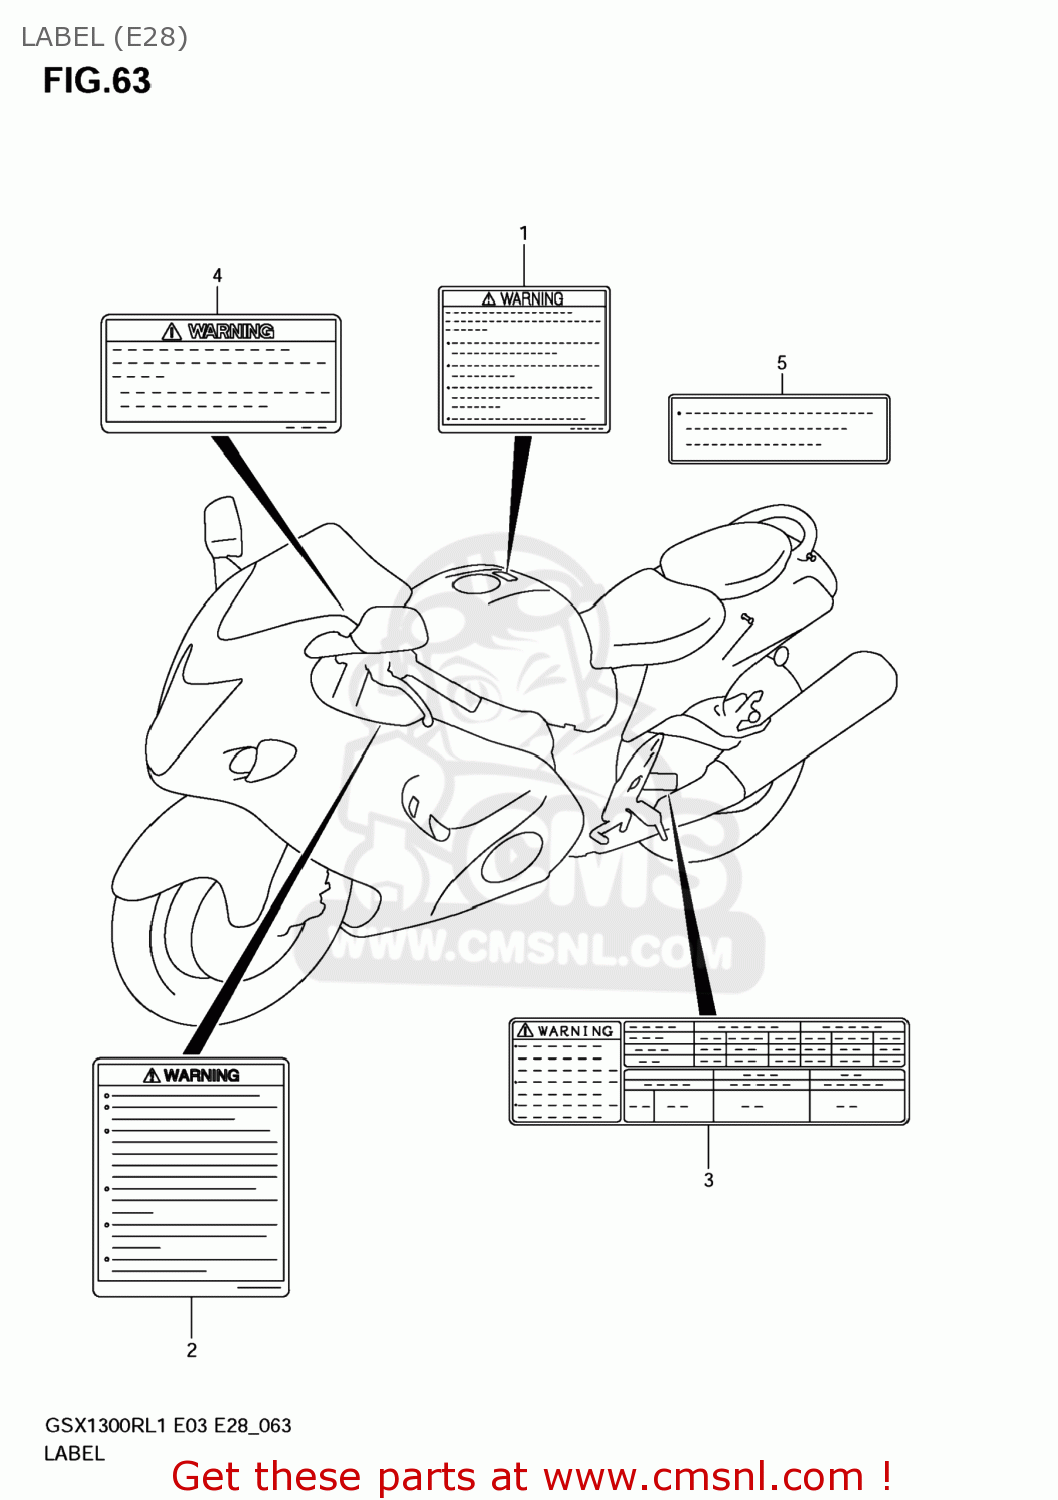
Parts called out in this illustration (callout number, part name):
1	LABEL,GENERAL WARNING
2	LABEL,SCREEN
3	LABEL,TIRE INFORMATION
4	LABEL,WARNING STEERING
5	LABEL,FUEL INFORMATION
6	MANUAL,OWNER'S
